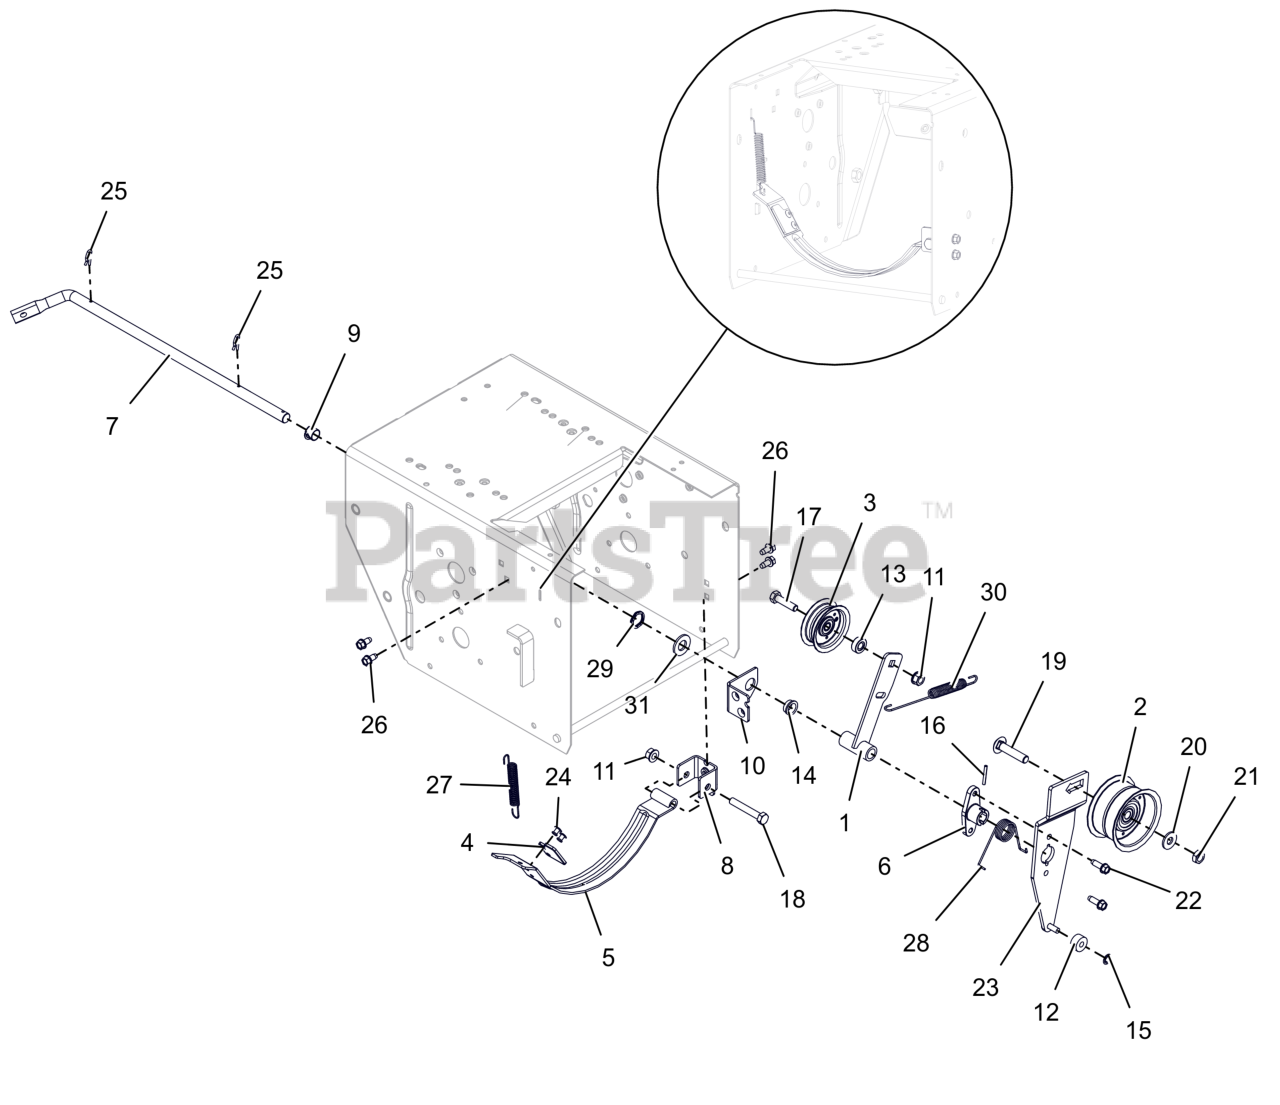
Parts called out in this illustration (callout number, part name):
1	ARM, IDLER-TRACTION
2	IDLER, FLANGE -2.75 OD X .375 ID
3	IDLER, FLAT - 2.00"
4	PAD, BRAKE
5	ARM, BRAKE-ATTACHMENT
6	HUB, BRAKE ARM
7	ARM, ATTACHMENT
8	PIVOT, BRAKE
9	BUSHING, POLYLINER-.50 SPLIT
10	BRACKET, SUPPORT
11	NUT-LK-TOP-FLG .312-18 GF ZCC
12	BSHG,SLV .265 X .625 X .375
13	SPCR, BRG .315X.500X.358X.281
14	BSHG,FLANGE .500X.625X.270X.75
15	RG-RTNG-EXT .250X.010
16	PIN-ROLL .125X1.00
17	BLT, HEX .31-18X1.25 G5 ZCC
18	BLT, HEX .31-18X2.00 G5 ZCC
19	BLT, RHSSN .38-16X1.75 G5 ZCC
20	WSHR,FLT .375X.875X.083 ZCC
21	NUT-LK-CTR-JAM .375-16 GB ZCC
22	SCR,TAP .25-20X.75 HWH TR ZCC
23	ARM, IDLER - ATTACHMENT
24	RVT, POP .1875 ZCC
25	CLIP, SPRING
26	SCR-TAP .25-20X.50 HWH ZCC
27	SPRING-EXT .437 X .438 X 2.64
28	SG-TORS .067X.88
29	WAVE SPRING .600X.875X.25FH
30	SG-TENS .06X.482X5.35
31	WSHR,FLT .531X1.062X.095 ZCC
